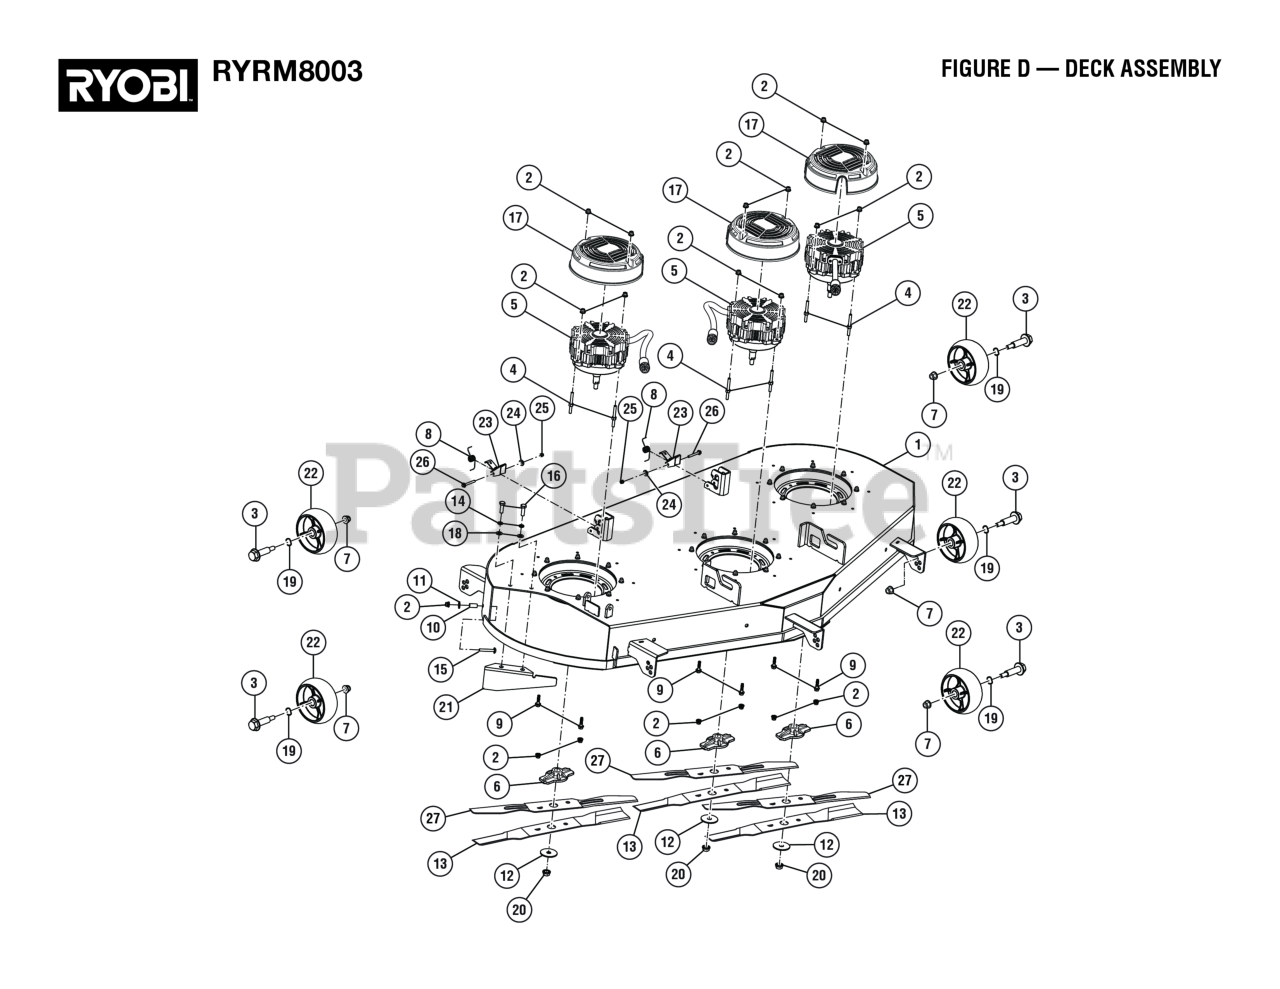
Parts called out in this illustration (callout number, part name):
1	Deck, 54 in.
2	Flange Lock Nut (M6 x 1.00)
3	Shoulder Bolt (M10 x 70 mm)
4	Threaded Stud (M6 x 35 mm)
5	Deck Motor
6	Crosscut Blade Adapter
7	Lock Nut (M10 x 1.5 mm)
8	Deck Clip Spring
9	Flange Bolt (M6 x 25 mm, Hex Hd.)
10	Deck Bagger Chute Mounting Shaft
11	Washer (OD18 x ID6.4 x 1.6t)
12	Blade Retainer Washer
13	Blade (18.5 in.)
14	Lock Washer (OD9.8 x ID8.5 x 5t)
15	Screw (M6 x 40, Soc Hd.)
16	Bolt (M8 x 25 mm, Hex Hd.)
17	Deck Motor Cover, Top
18	Washer (OD16 x ID8.4 x 1.6t)
19	Spring Washer (OD20.5 x ID17 x 0.3t)
20	Flange Lock Nut (M10 x 1.25)
21	Deck Baffle
22	Front Deck Roller Wheel (124.5 Dia.)
23	Deck Clip Latch
24	Washer (OD12 x ID5.3 x 1t) (For Main Relay G and Power Converter I)
25	Flange Nut (M5)
26	Bolt (M5 x 45 mm)
27	Crosscut Blade
